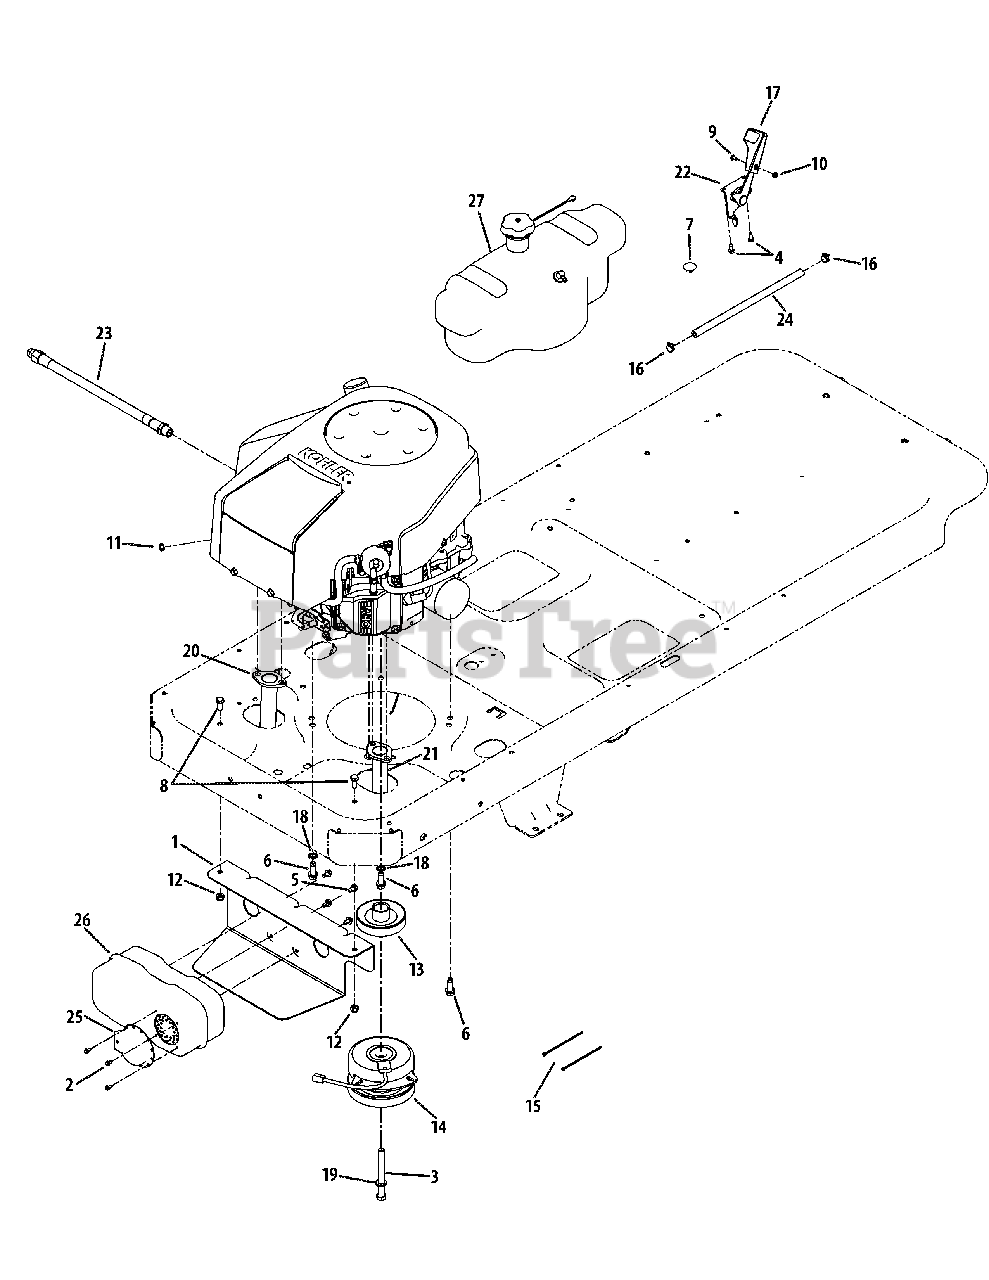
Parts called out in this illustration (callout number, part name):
1	Muffler Mounting Bracket
2	Hex Washer Screw, #8-18 x .5
3	Hex Screw, 7/16-20 x 3.50
4	Hex Washer Screw, #12-16 x .5
5	Hex Washer Screw, 1/4-20 x .5
6	Hex Washer Screw, 3/8-16 x 1.000
7	Choke Plug
8	Hex Screw, 5/16-18 x .75
9	Machine Screw, #8-32 x .375
10	Hex Nut, #8-32
11	Hex Nut, 1/4-20
12	Hex Lock Nut, 5/16-18
14	Electric PTO Clutch
15	Clutch Wire Tie
16	Hose Clamp
17	Throttle Control
18	Lock Washer, 3/8
19	Lock Washer, 7/16
20	Exhaust Pipe, LH
21	Exhaust Pipe, RH
22	Throttle/Choke Cable
23	Oil Drain Extension Hose
24	Fuel Line Hose
25	Muffler Deflector
26	Muffler
27	Fuel Tank Assembly
27	Fuel Tank Bushing
27	Fuel Pick-Up Fitting
27	Fuel Tank
27	Fuel Cap
